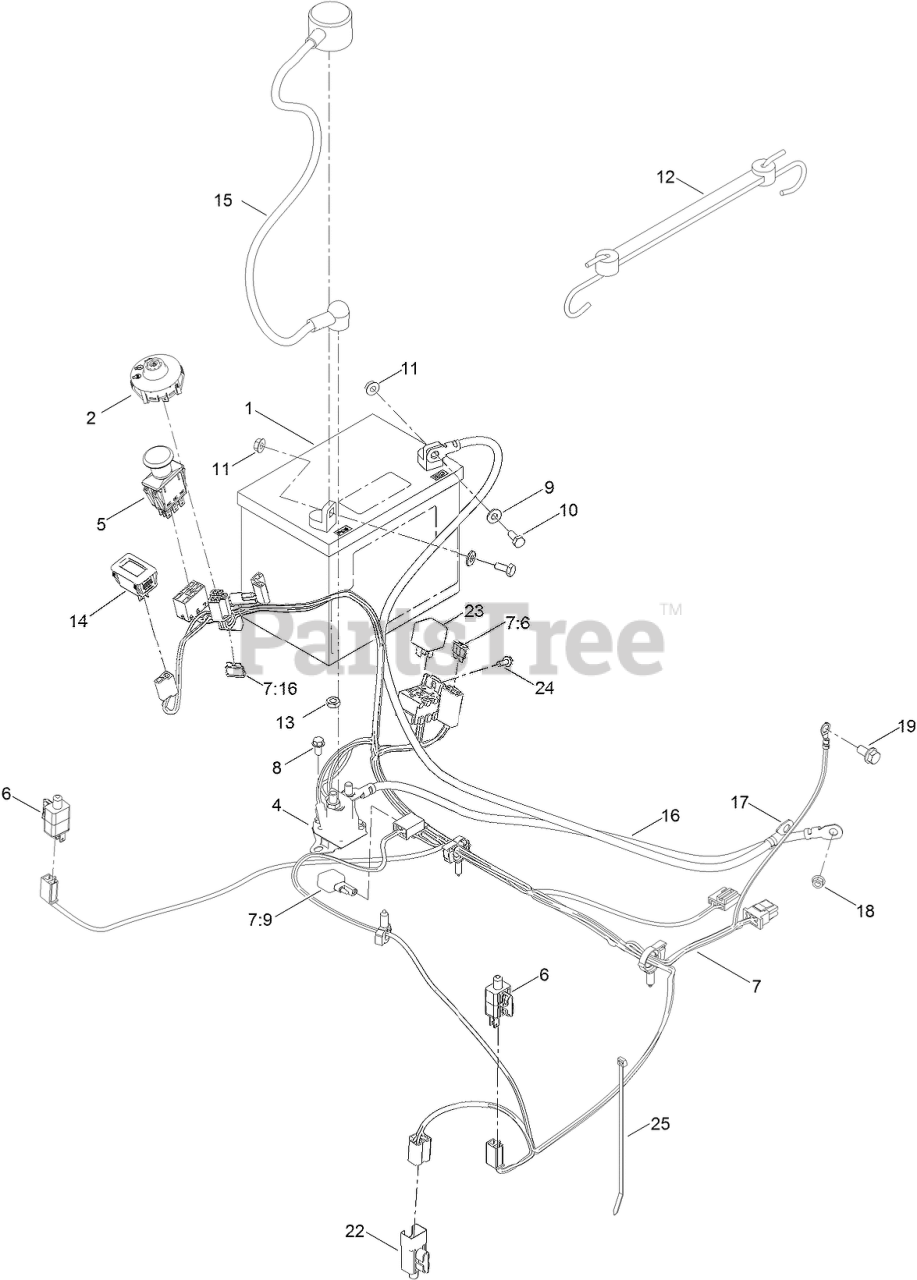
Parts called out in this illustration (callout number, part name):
1	BATTERY-DRY
2	SWITCH-IGNITION
4	SOLENOID
5	SWITCH-PTO
6	SWITCH
7	HARNESS-WIRE
7:6	FUSE-BLADE, 25 AMP
7:16	FUSE-BLADE, 15 AMP
8	SCREW-HWH
9	WASHER-FLAT
10	SCREW-HH
11	NUT-HF
12	HOLDDOWN-BATTERY
13	NUT-HJ
14	HOURMETER
15	CABLE-BATTERY, POSITIVE
16	CABLE-BATTERY, POSITIVE
17	CABLE-BATTERY, NEGATIVE
18	NUT-HF
19	SCREW-HHF
22	SWITCH-REVERSE
23	RELAY
24	SCREW-TAPTITE
25	TIE-CABLE
